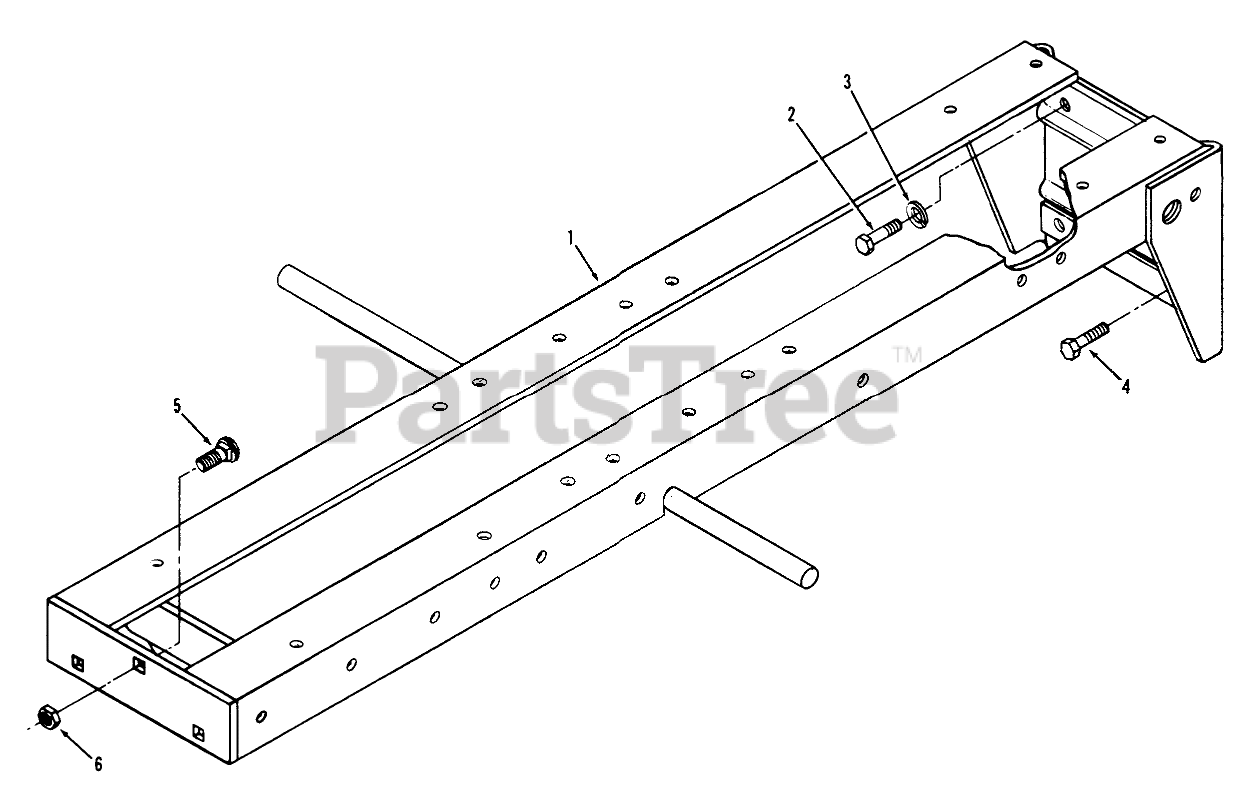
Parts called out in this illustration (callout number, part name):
1	Assy-Frame
2	Bolt
3	LOCKWASHER
4	Bolt
5	Bolt
6	Nut
